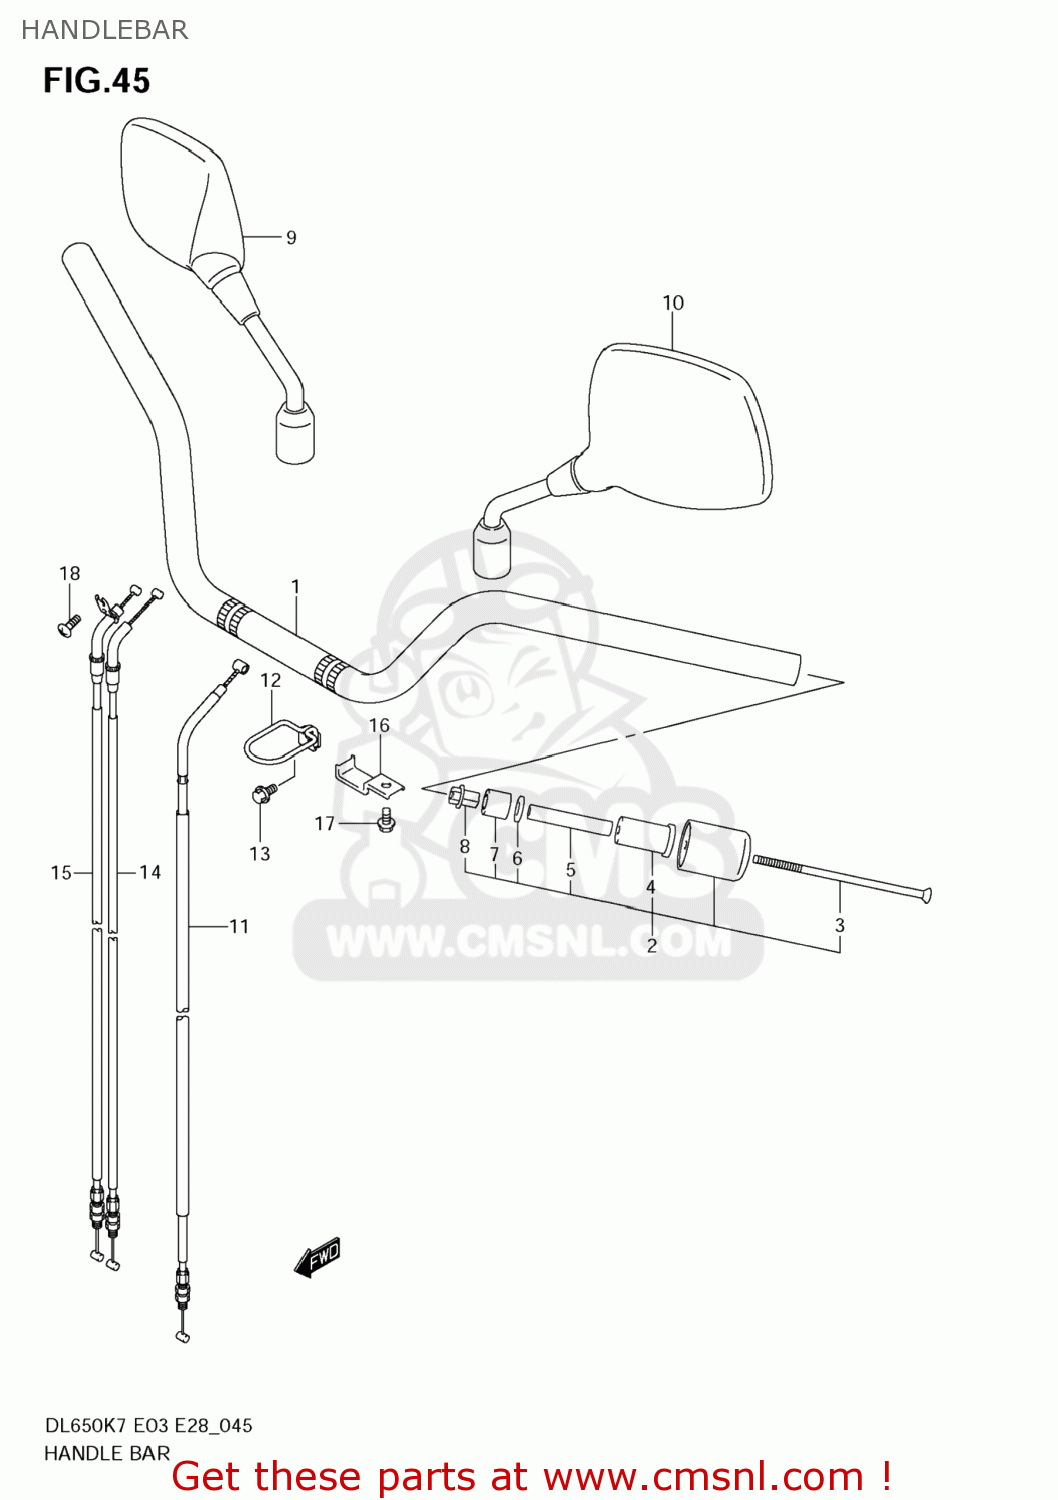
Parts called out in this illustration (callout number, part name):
1	HANDLEBAR
2	BALANCER SET,HANDLEBAR
3	SCREW(6X110)
4	EXPANDER
5	SPACER,EXPANDER
6	WASHER(6.5X16X4)
7	EXPANDER,HANDLE BALANCER
8	NUT,HANDLE BALANCER
9	MIRROR ASSY,RE
10	MIRROR ASSY,LH
11	CABLE ASSY,CLUTCH
12	GUIDE,CLUTCH CABLE
13	BOLT
14	CABLE ASSY,THROTTLE NO.1
15	CABLE ASSY,THROTTLE NO.2
16	GUIDE,THROTTLE CABLE
17	SCREW
18	SCREW
